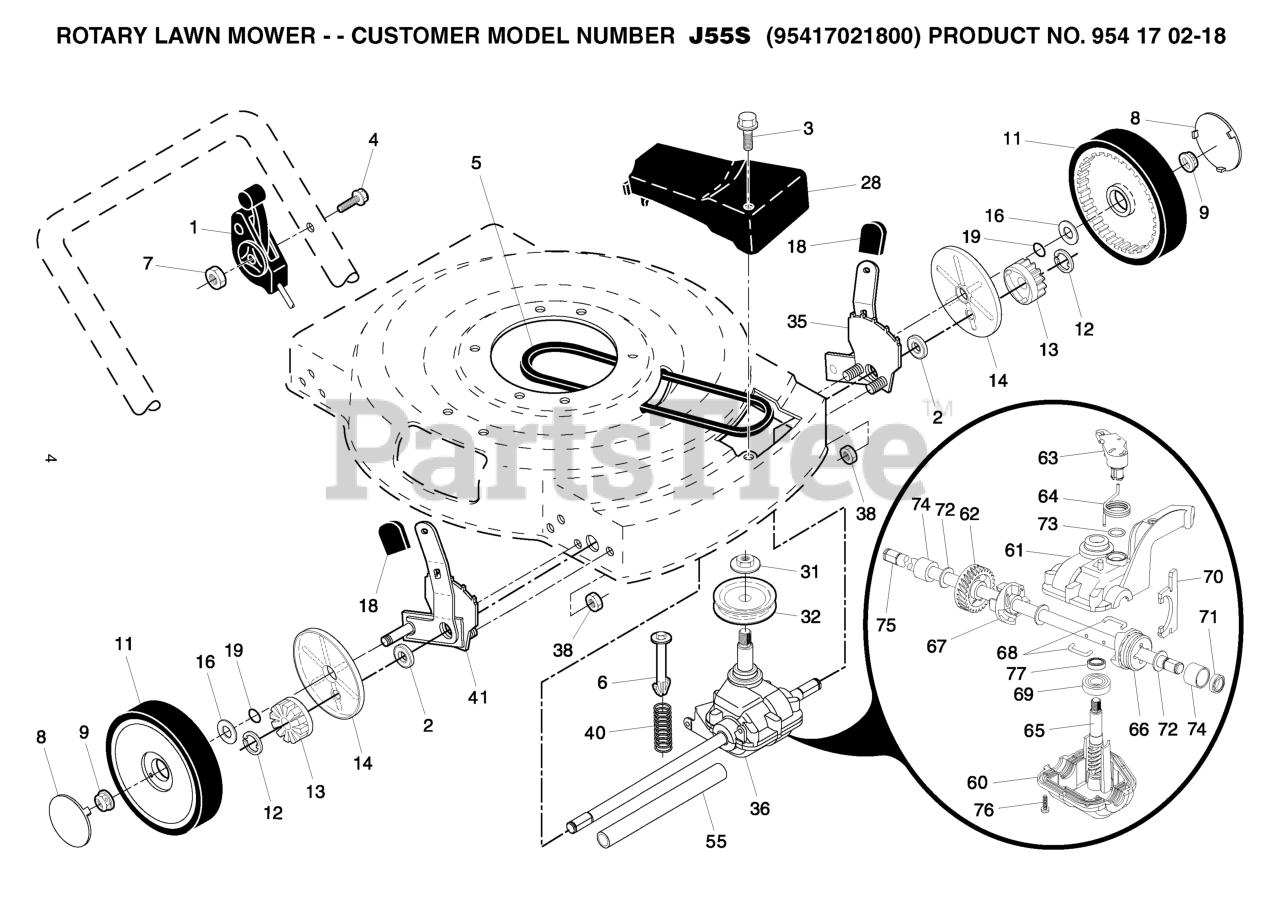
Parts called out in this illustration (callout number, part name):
1	DRIVE CONTROL 59.8 FWGD
2	BEARING ASM
3	Screw, Tapping, Pan Head #10-24 x 2-3/4
4	SCREW.PAN.HEAD
5	BELT THERM .32
6	SPRING RETAINER
7	NUT.HEX.FLANGE.1/4
8	HUBCAP.8".GREY
9	HEX FLANGE LOCKNT
11	RP WHEEL.8X2.RADIAL.GRAY
12	E-RING 7/16 RE
13	PINION GEAR
14	COVER.DUST.WHEEL
16	WASHER FLUT
18	SELECTOR KNOB
19	O-RING
28	Drive Cover
31	FLANGED LOCKNUT 3/8-16 ZINC
32	PULLEY, DRIVE
35	WHEEL ADJUSTER ASSY (LEFT)
36	TRANSMISSION 22RD
38	LOCKNUT.NYLOC.1/4-20
40	SPRING.EXTENSION
41	WHEEL ADJUSTER KIT RH
55	DRV SHAFT TUBE PM
60	LOWER CASE
61	UPPER CASE
62	GEAR.27.TEETH.WALK.MOWER
63	LEVER, CLUTCH
64	SPRING, RETURN
65	SHAFT INPUT (13041)
66	DOG, MOVABLE (11032)
67	DOG, FIXED GT11031
68	WIRE, FORMED (15966)
70	FORK, SHIFT
71	SEAL.OUTPUT.SHAFT
73	SEAL, CASE O-RING
77	SEAL INPUT SHAFT
